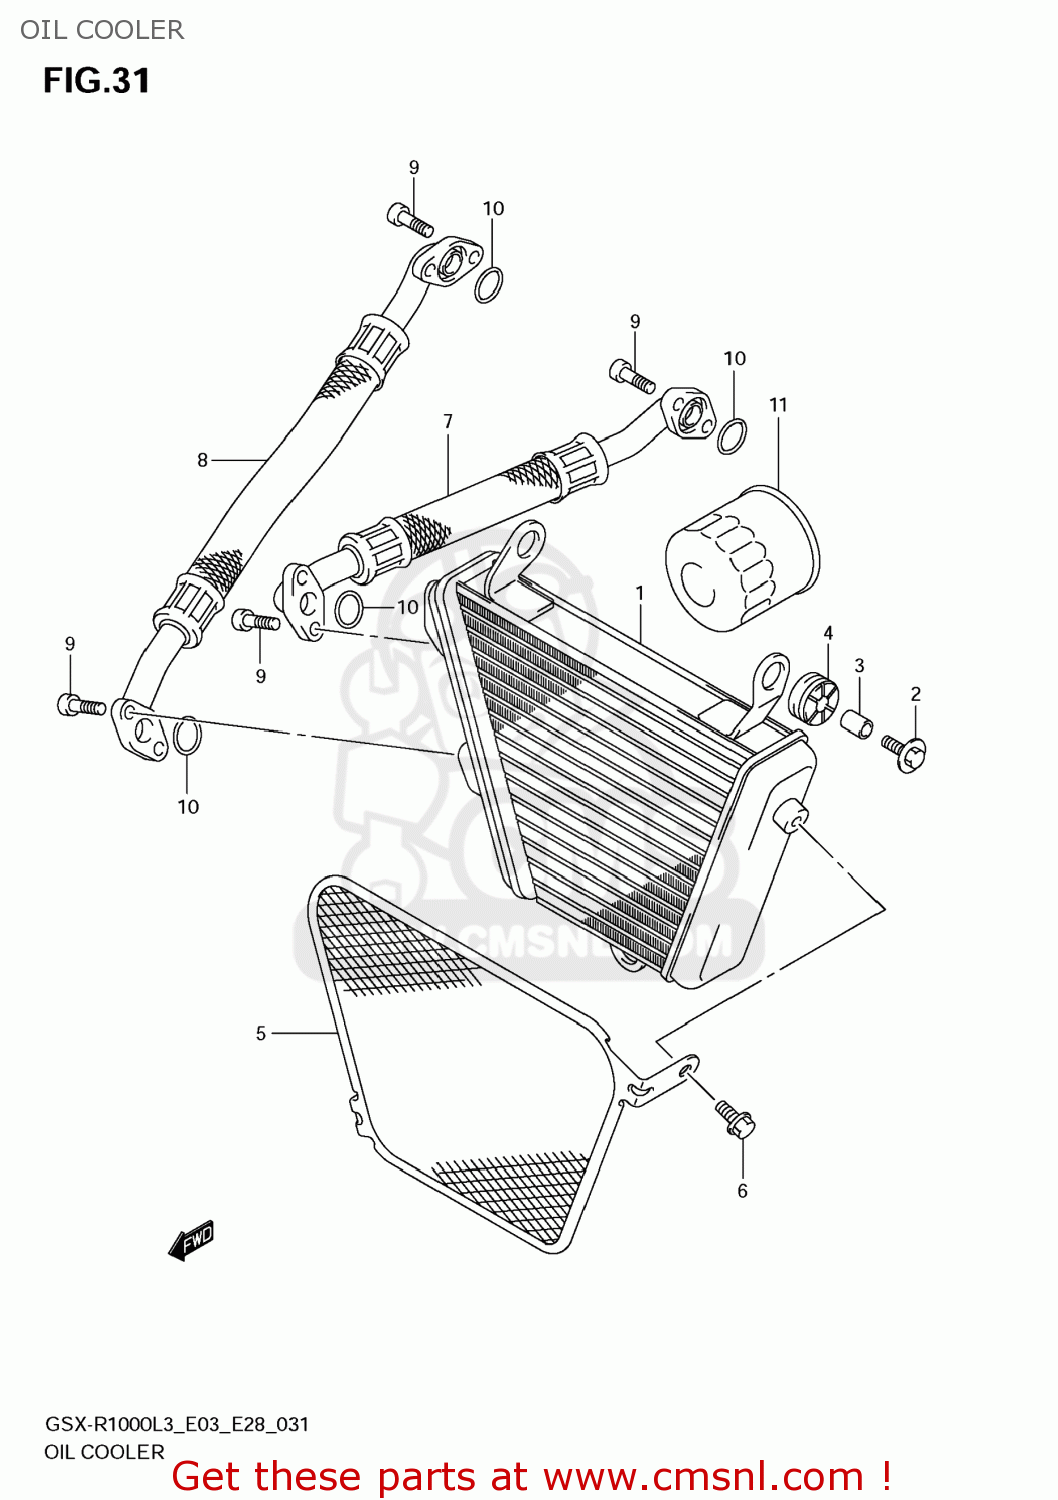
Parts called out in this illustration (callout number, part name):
1	COOLER ASSY,OIL
2	BOLT(6X25)
3	SPACER(6.5X10X12)
4	CUSHION
5	GUARD,OIL COOLER
6	BOLT
7	HOSE,OIL COOLER INLET
8	HOSE,OIL COOLER OUTLETLET
9	BOLT(6X16)
10	O RING(D:2.4,ID:16)
11	FILTER ASSY,ENGINE OIL
